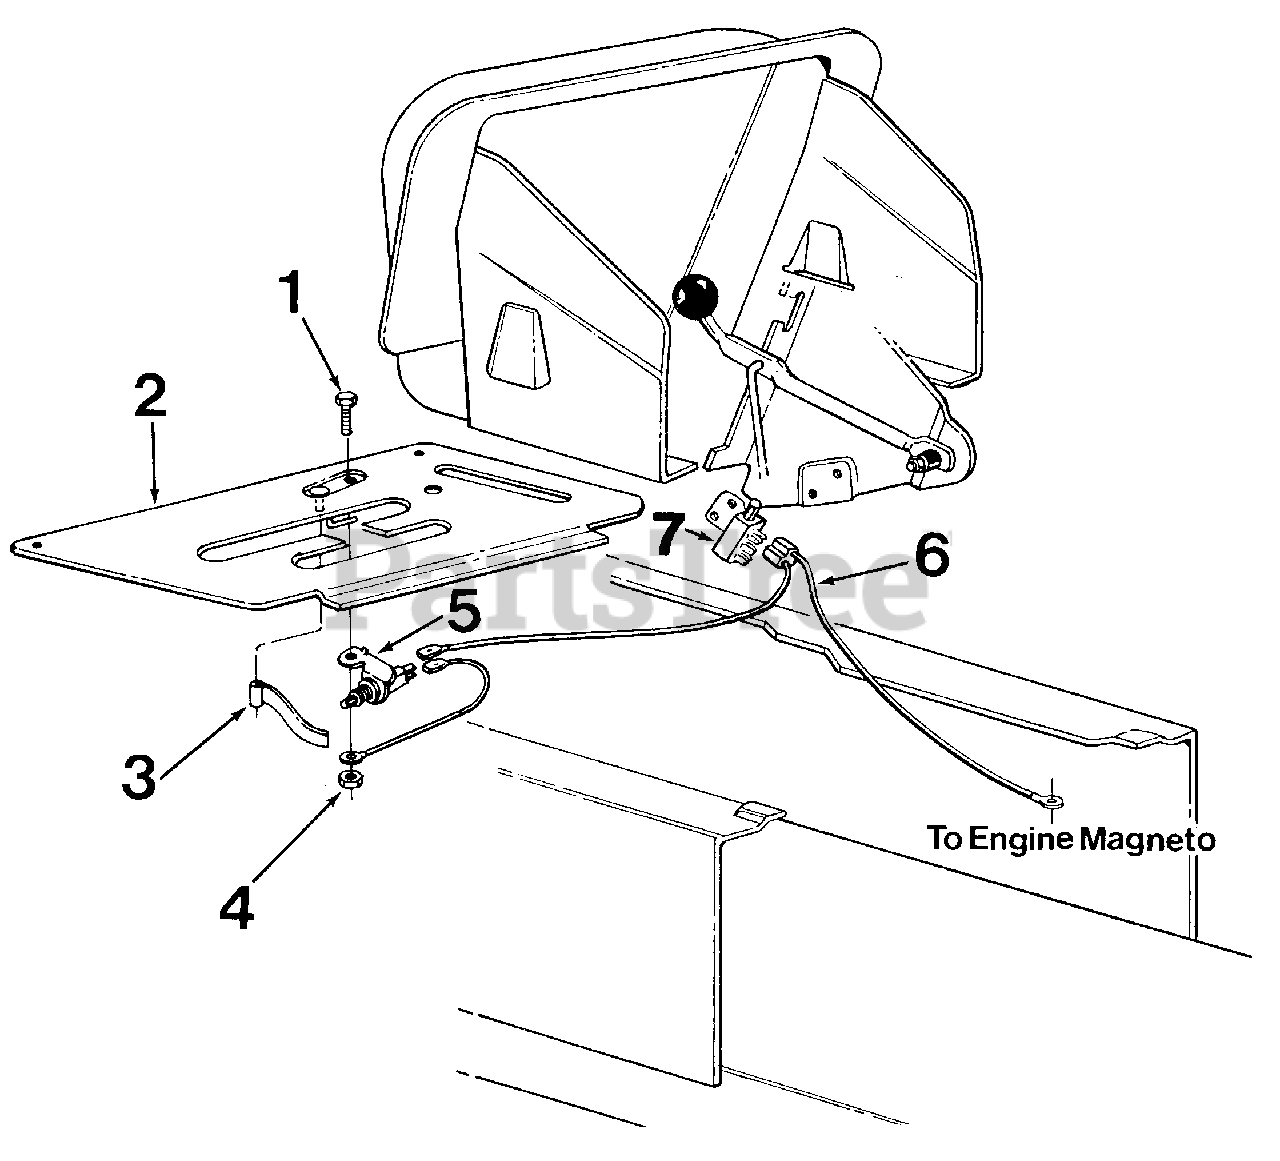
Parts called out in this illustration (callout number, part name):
1	Hex Bolt 1/4-20 x .50" Lg.
2	Transmission Cover Ass'y.
3	Switch Actuator Spring Lever
4	Hex Nut 1/4-20 Thd.
5	Safety Switch
6	Reverse Lockout Wire Harness
7	Safety Swi tch
